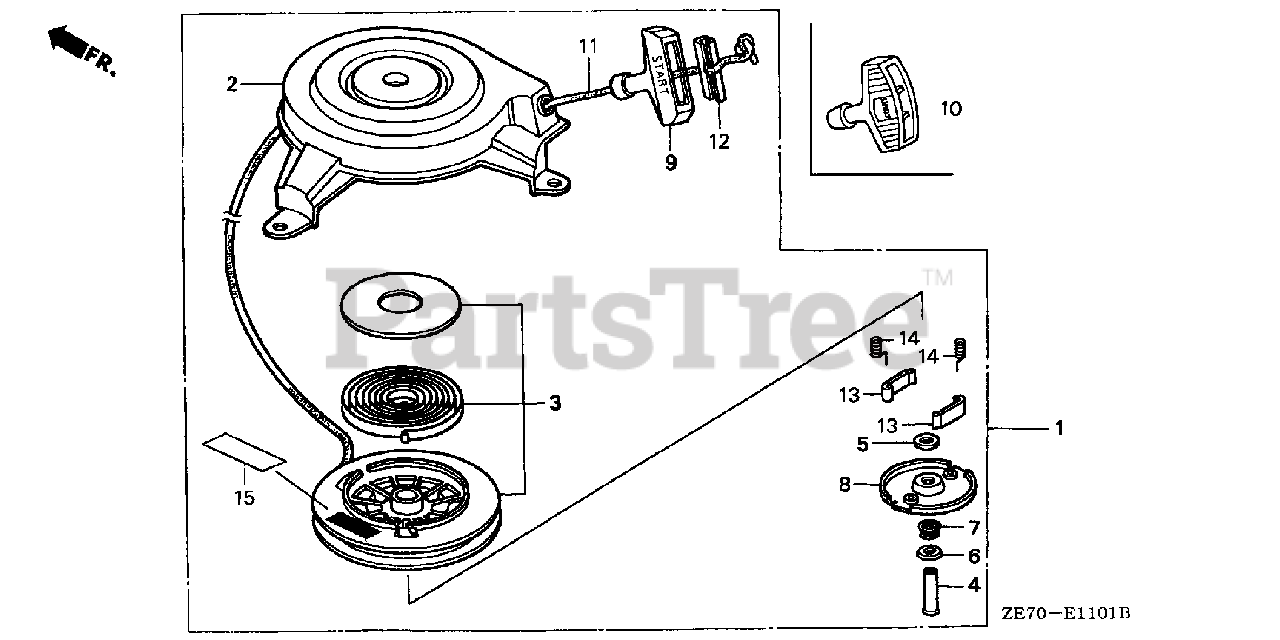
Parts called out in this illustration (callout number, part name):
1	STARTER ASSY., RECOIL
2	HOUSING ASSY. (NA USE ALT:28400-ZG9-803)
3	PULLEY & SPRING ASSY.
4	PIN, CENTER
5	PLATE A, FRICTION
6	PLATE B, FRICTION
7	SPRING, FRICTION
11	ROPE, RECOIL STARTER
12	HANDLE, REINFORCEMENT
14	SPRING, DOG
